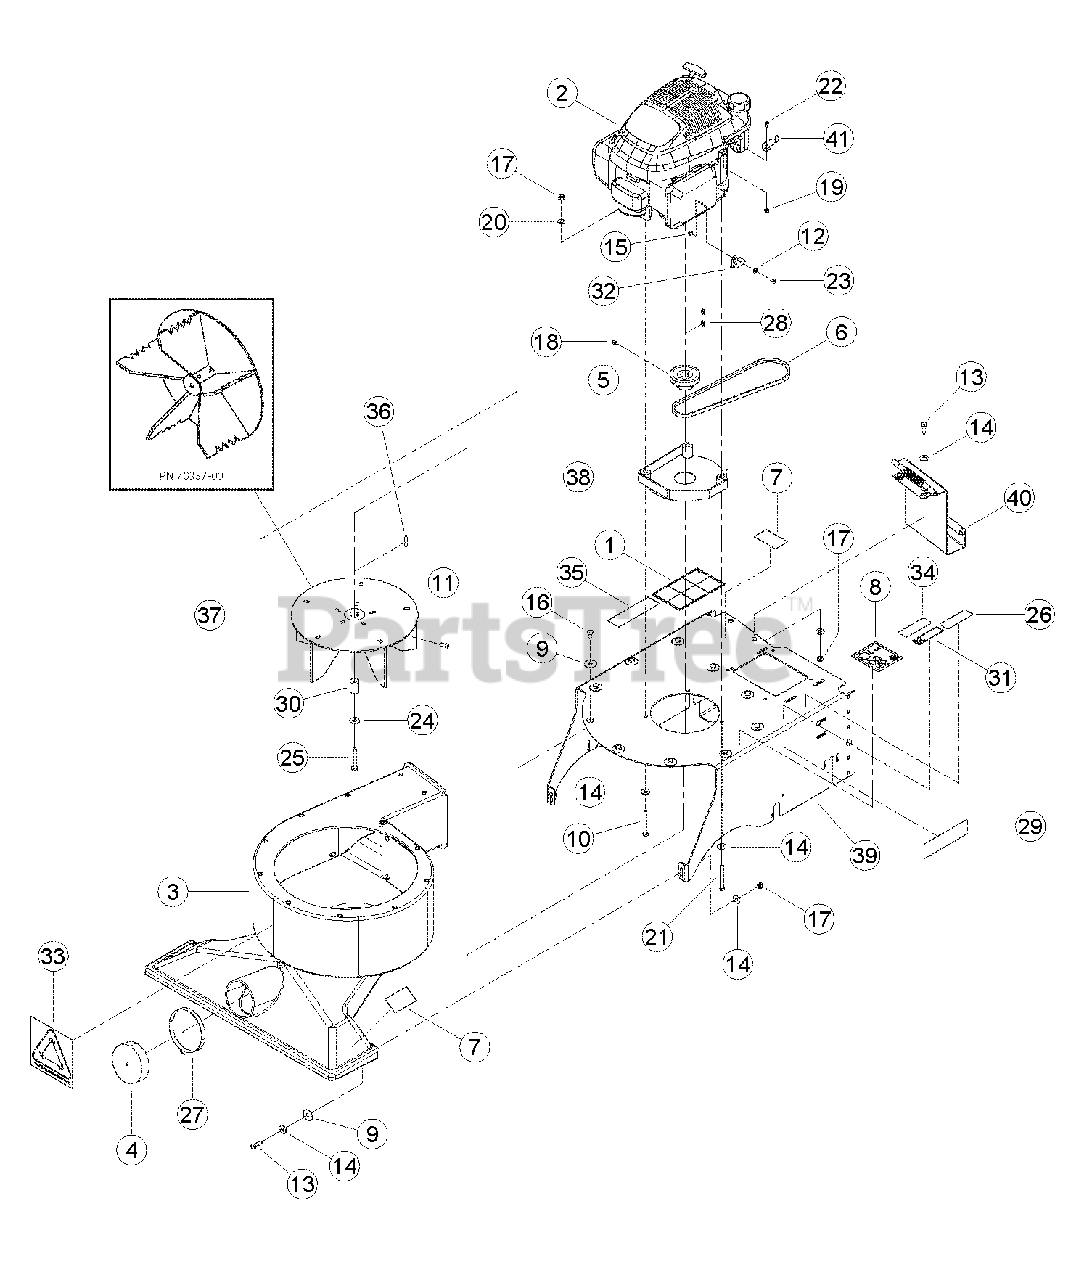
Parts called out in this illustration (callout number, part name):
1	DECAL, PROTECTION
2	ENGINE, 5.5 HP HONDA GCV (FOR SERVICE SEE ENGINE OWNER'S MANUAL OR YOUR NEAREST AUTHORIZED HONDA ENGINE DEALER)
2	ENGINE, 190CC B&S INTEK/IC VERTICAL (FOR SERVICE SEE ENGINE OWNER'S MANUAL OR YOUR NEAREST AUTHORIZED B&S ENGINE DEALER)
3	ASSY, FAN HOUSING W/INTAKE
4	CAP, ROUND VINYL (4 X 1)
5	PULLEY, 2.85 O.D. X 7/8 IN BORE
6	BELT, SP BEARVAC (3L32)
7	DECAL, DANGER
8	DECAL, 97 DB
8	DECAL, 98 DB
9	WASHER, 5/16 FENDER
10	BOLT, 5/16 X 3 HEX HD GR5 ZP
10	BOLT, 5/16 X 2-3/4 HCPS GR5
11	SCREW, 5/16-18 X 5/8 SQ HD SET
12	WASHER, #8 SAE FLAT
13	BOLT, 5/16 X 1 HEX HD
14	WASHER, 5/16 FLAT
15	NUT, #8 X 32 NYLOCK
16	BOLT, 5/16 X 5/8 HEX HD
17	NUT, 5/16 NYLOCK
18	SCREW, 5/16 X 3/8 SET
19	NUT, 10/24 NYLOCK TYPE NM ZP
20	WASHER, 5/16 SAE FLAT
21	BOLT, 5/16 X 4 HHCS GR5 ZP
22	SCREW, MCH 10-24 X 1/2 PAN HD PH ZP
23	SCREW, #8 X 32 X 3/4 PAN PHP ZP
24	WASHER, 3/8 GR8 USS ZP
25	BOLT, 3/8 NC X 2-1/4 HHCS NF GR8 ZP
26	DECAL, SERIAL NUMBER
27	CLAMP, 4 IN HOSE
28	KEY, 3/16 X 5/32 4 MM WDRFF JUMP
29	DECAL, ECHO BEARCAT 6.82 X 1.90
30	SPACER, .88 X 1.25
31	DECAL, 5.5 HP SP BEARVAC INFORMATION
31	DECAL, 6 HP SP BEARVAC INFORMATION
32	SWITCH, HONDA ENGINE KILL
33	DECAL, COLLECT IT
34	DECAL, ATLANTIC BRIDGE LTD INFO
35	DECAL, MODEL WV190S
36	KEY, 3/16 X 1-1/4 SQUARE
38	WELDMENT, BEARVAC ENGINE SUPPORT
39	SUPPORT, BEARVAC FRAME
40	ASSEMBLY, EXHAUST DOOR
41	PLATE, HONDA BRACKET HOLDER
